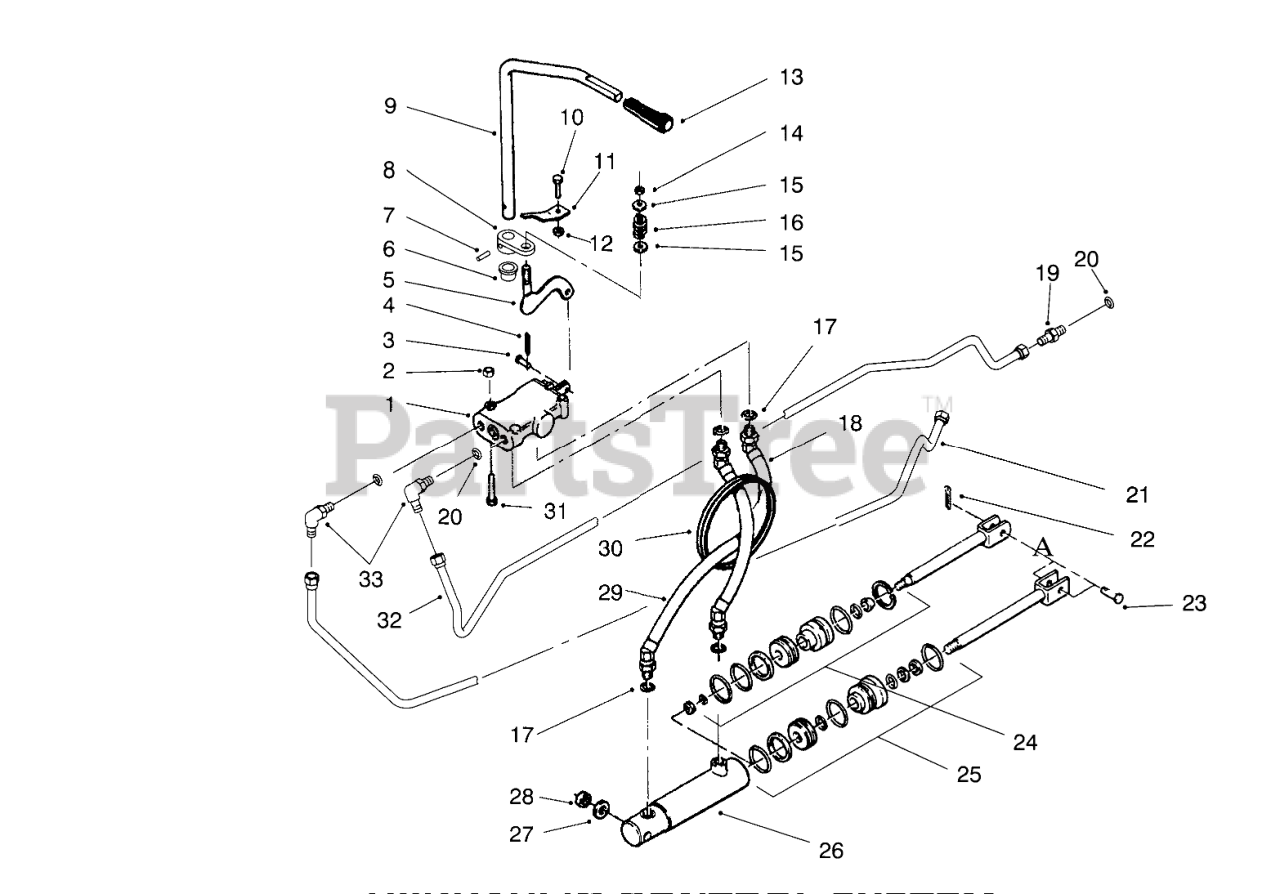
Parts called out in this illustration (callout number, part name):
1	Valve-Hydraulic (Incl. Ref.#3-4)
2	NUT-LOCK, NI
3	PIN-CLEVIS
4	PIN-COTTER
5	WLDMT-LIFT BAR
6	NYLINER BUSHING
7	SPIROL PIN 7/32X7/8
8	ARM-CONTROL
9	ROD-LIFT CONTROL
10	SCREW-HH
11	BRACKET-CONTROL R B
12	NUT-LOCK, NI
13	KNOB-HYDRAULIC LIFT
14	NUT-LOCK, NI
15	WASHER-PLAIN
16	SPRING
17	O RING
18	Hose ASM-Hydraulic
19	Fitting-Straight Adapter (Incl. Ref. #20)
20	0-Ring
21	TUBE-HYD PRESSURE
22	PIN-COTTER
23	Pin-Clevis
24	S/A O-RING&GASKET AS
25	S/A 108872 HYD CYL
26	Cylinder-Hydraulic (Incl. Ref.#24-25)
27	Washer
28	SPACER-OUTER
29	Hose ASM-Hydraulic
30	GROMMET
31	SCREW-HH
32	TUBE-HYD RETURN
33	Fitting-90 (Incl. Ref. #20)
